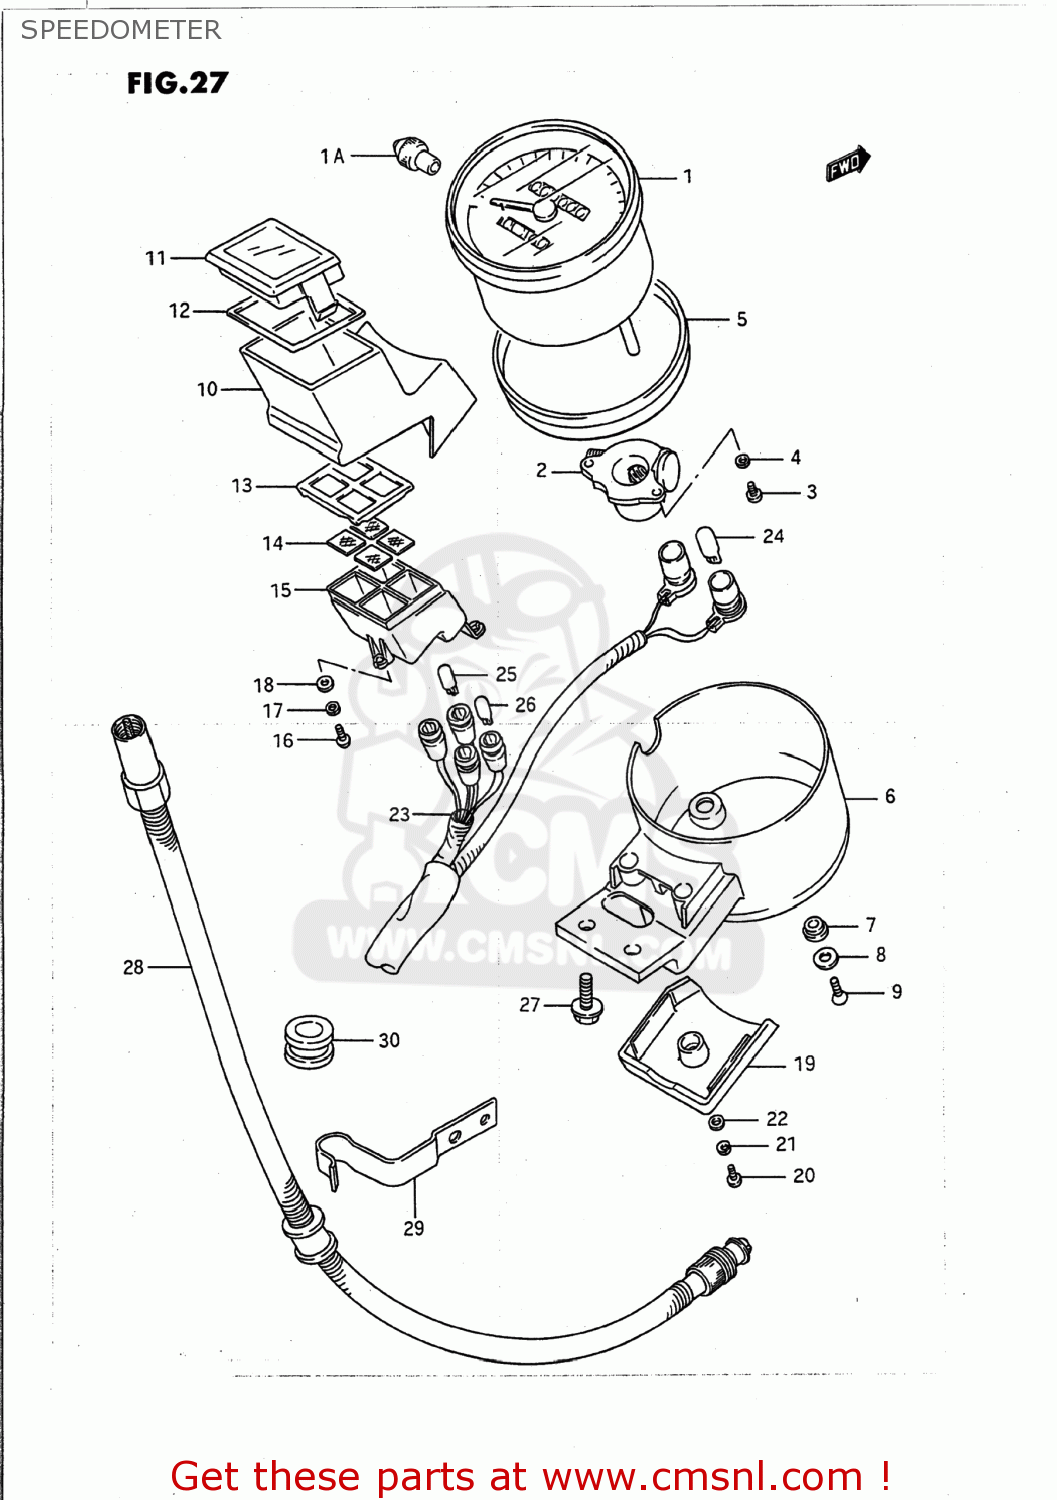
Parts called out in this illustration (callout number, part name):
1	SPEEDOMETER ASSEMBLY
1A	KNOB,TRIP
2	BOX,GEAR
3	SCREW
4	WASHER,LOCK 4M
5	CUSHION
6	COVER,METER
7	CUSHION,METER
8	WASHER
9	SCREW
10	BOX,PILOT
11	LENS,PILOT BOX
12	CUSHION
13	PLATE,PILOT LENS
14	LENS SET
15	CASE,PILOT LAMP
16	SCREW
17	WASHER,LOCK
18	WASHER
19	COVER,PILOT BOX
20	SCREW
21	WASHER,LOCK 4M
22	WASHER
23	SOCKET,METER
24	BULB(12V3.4W,T10)
25	BULB(12V3W,T6.5)
26	BULB(12V1.7W,T6.5)
27	BOLT
28	CABLE ASSY,SPEEDOMETER
29	CLAMP,SPEEDOMETER CABLE
30	GROMMET
